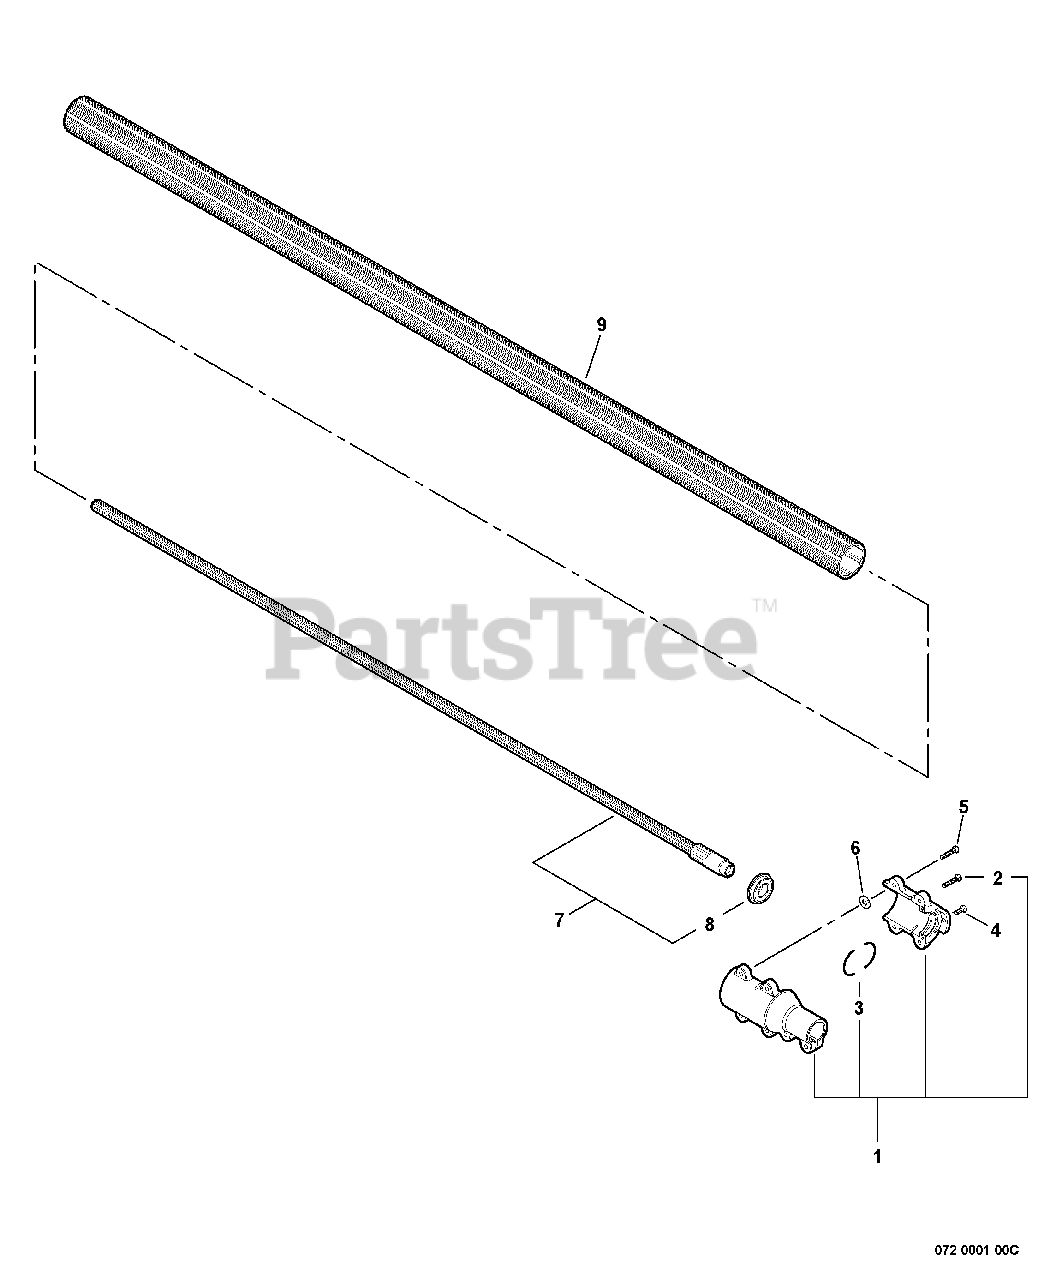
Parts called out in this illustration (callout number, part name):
1	COUPLING ASSY
2	SCREW - 5X20
3	CUSHION
4	SCREW - 5X14
5	SCREW - 5X20
6	WASHER - 5
7	DRIVESHAFT ASSY - LOWER
8	BEARING, BALL - 6002
9	PIPE, MAIN - ORANGE
